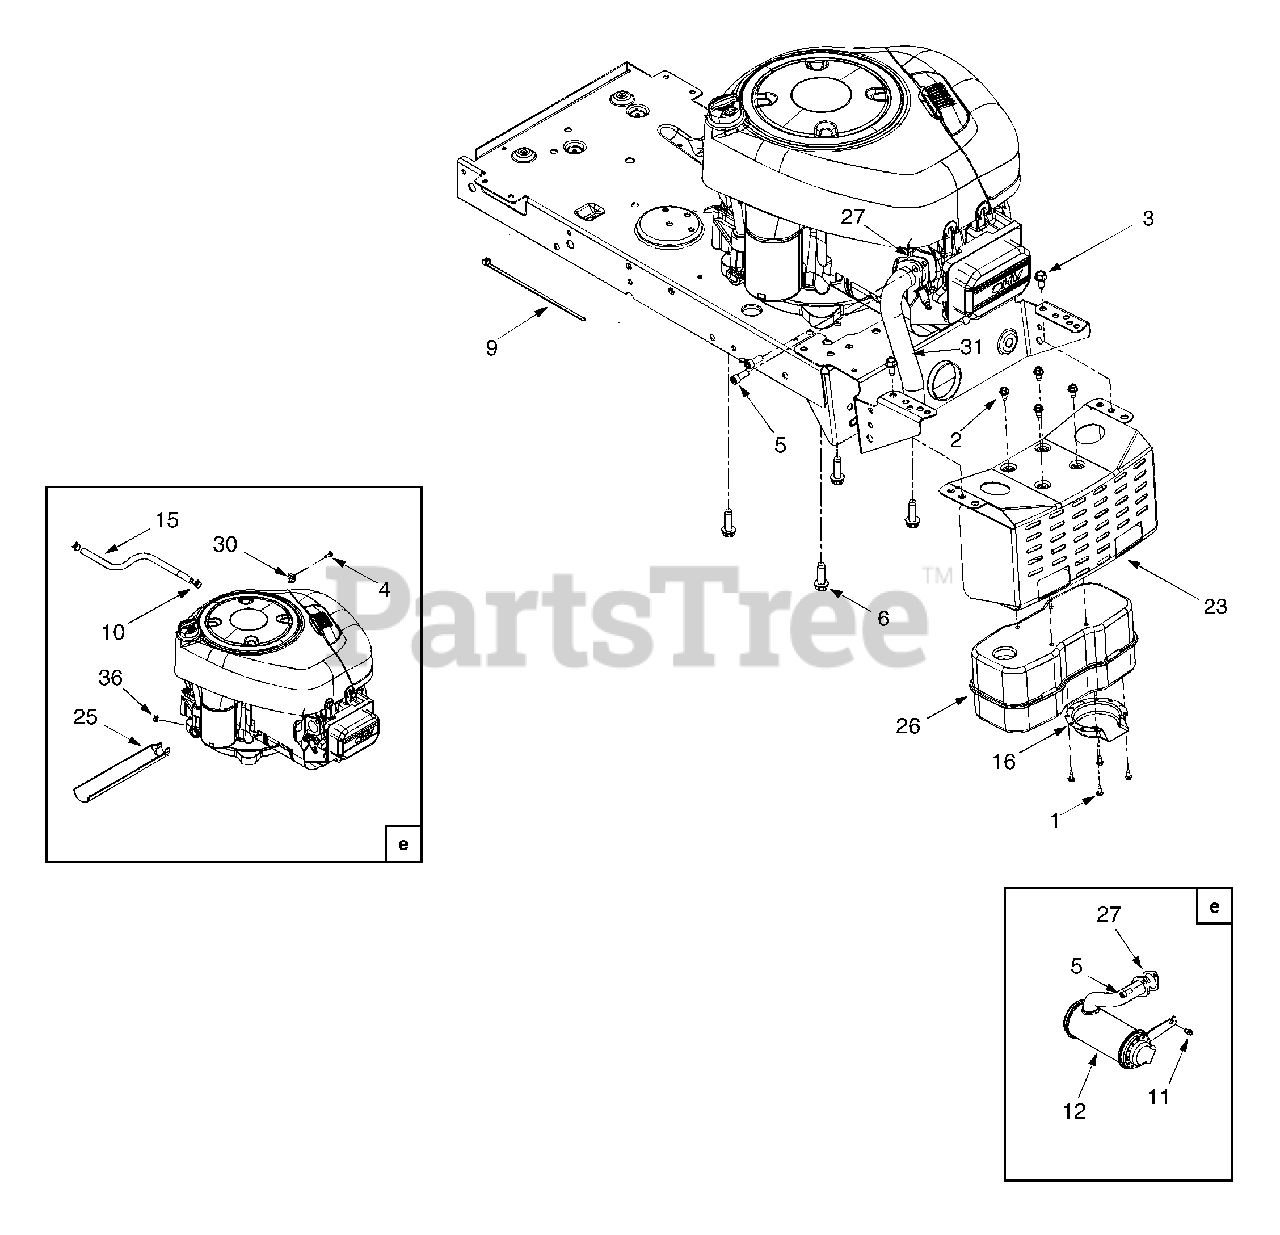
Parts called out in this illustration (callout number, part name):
1	Screw, #8-32, .375
2	Self-tapping Screw, 1/4-14, .625
3	Self-tapping Screw, 5/16-12, .75
4	Screw, #10-32, .625
5	Socket Cap Screw, 5/16-18, .625
6	Self-tapping Screw, 3/8-16, 1.25
9	Cable Tie, 7.4"
10	Hose Clamp, .490
11	Screw, 1/4-20, 0.500
12	Muffler, Exhaust
15	Fuel Line Hose
16	Muffler Deflector
25	Oil Drain Sleeve
26	Muffer, Single Inlet
26	Muffer w/welded Exhaust Pipe, Single Inlet
27	Exhaust Gasket
30	Casing Clamp
31	Exhaust Pipe
36	Hex Sems Nut, 1/4-20
